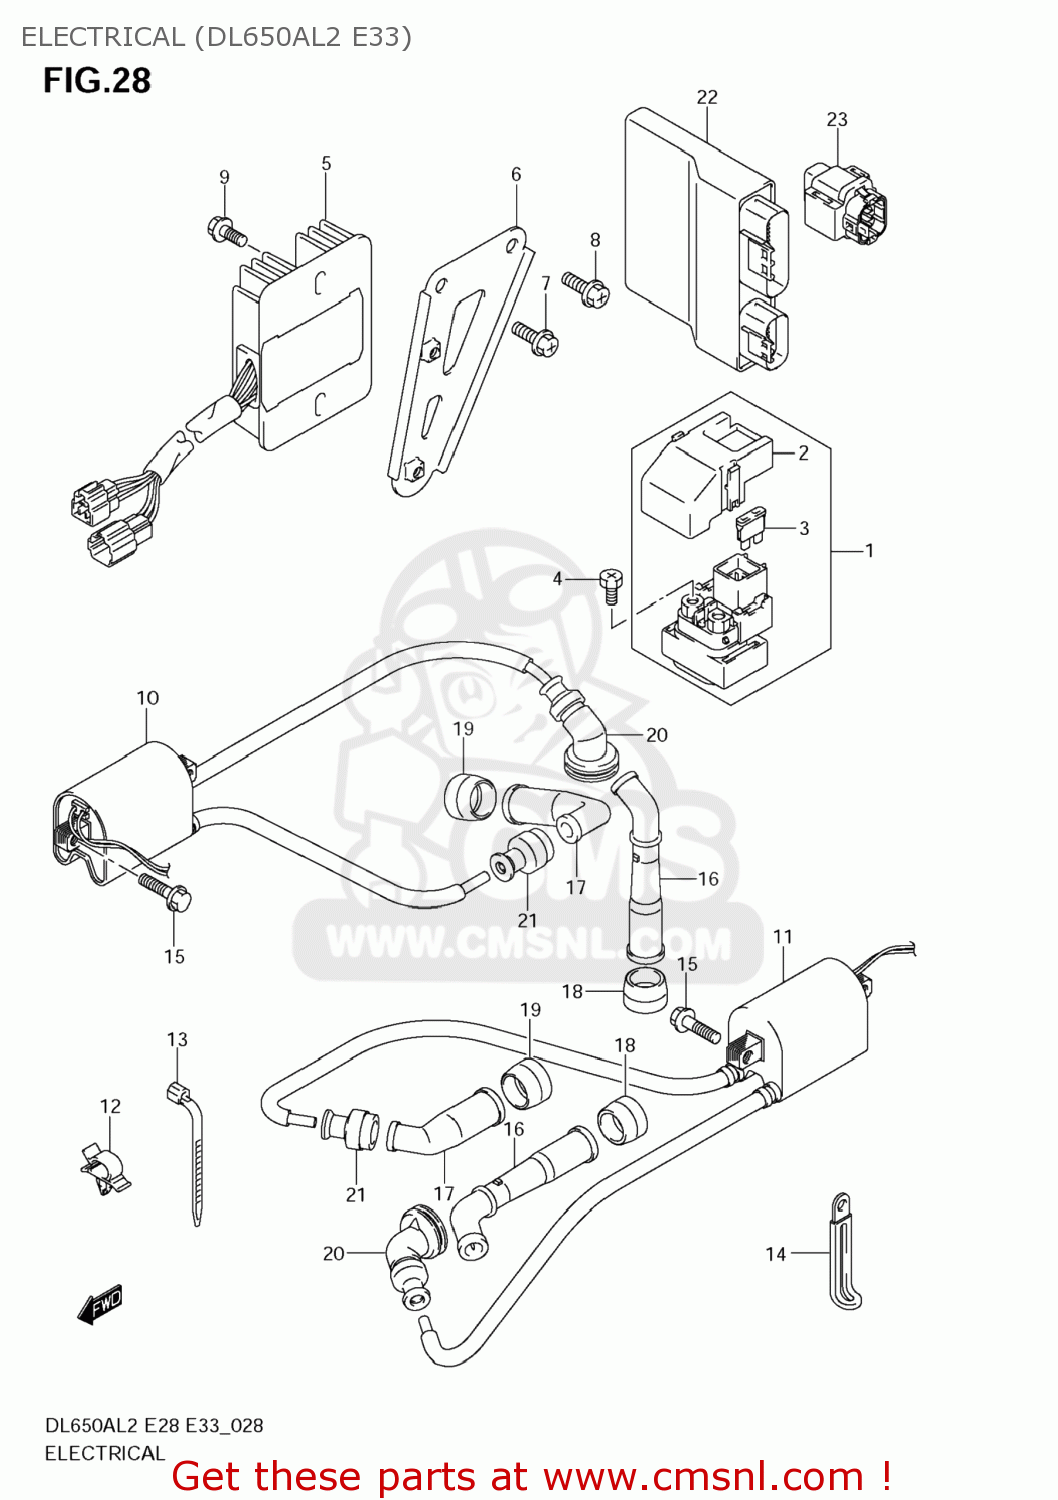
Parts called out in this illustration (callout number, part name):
1	RELAY ASSY,STARTING MOTOR
2	COVER
3	FUSE(30A)
4	SCREW(6X8)
5	RECTIFIER ASSY
6	BRACKET,RECT FTG
7	SCREW
8	SCREW
9	SCREW
10	COIL ASSY,IGNITION FR
11	COIL ASSY,IGNITION RR
12	CLAMP
13	CLAMP(L:165)
14	CLAMP(L:45)
15	BOLT
16	CAP ASSY,SPARK PLUG
17	CAP ASSY,SPARK PLUG
18	SEAL,SPARK PLUG
19	SEAL,SPARK PLUG
20	SEAL,HIGH TENSION CORD CTR
21	SEAL,HIGH TENSION CORD
22	CONTROL UNIT,FI
23	SENSOR ASSY,FUEL CUT
